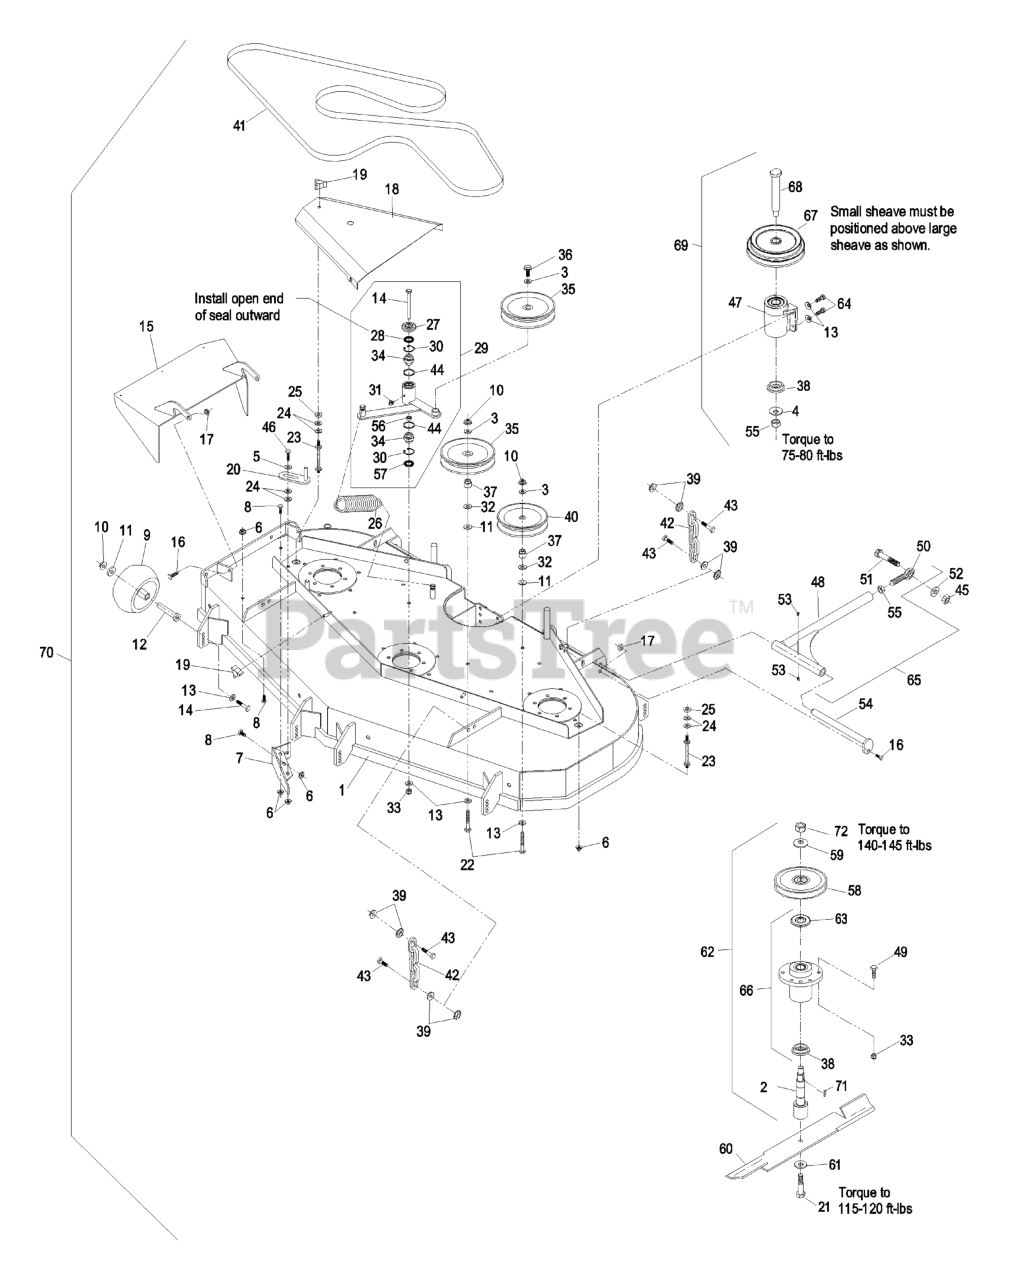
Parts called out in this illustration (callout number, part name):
1	ASM,DECK W/DECALS XP604
2	SPINDLE,SHORT
3	WASHER-FLAT
4	WASHER-SPRING
5	WASHER-SPRING
7	WLD,BAFFLE DISCHARGE
8	SCREW-HH
9	ROLLER-SCALP, ANTI
10	NUT-HHF, WHIZ
12	BUSHING-ROLLER
13	WASHER-BELLEVILLE
14	SCREW-HH
15	WLD,CHUTE XP604
16	SCREW-HH
17	NUT-LOCK, NI
18	SHIELD,BELT
19	KNOB-3 PRONG
20	GUIDE-BELT
21	SCREW-CAP
22	SCREW-HH
23	STUD-SHIELD, BELT (SHORT)
24	WASHER-FLAT
27	GUARD-TOP
28	SEAL-LIP, SINGLE
29	KIT,DECK IDLER LZ/XP
30	RING-SNAP
31	FITTING-GREASE, 90 DEG
32	WASHER-FLAT
33	NUT-LOCK, NI
34	BEARING-SPHERICAL
36	SCREW-HHF
37	BUSHING-IDLER
38	SPACER-GUARD, BOTTOM
40	PULLEY-IDLER
41	BELT,BLADE DRIVE
42	CHAIN-LIFT, DECK
43	SCREW-HH
45	NUT-HEX
46	SCREW-HH
49	SCREW-HH
50	BALLJOINT-SPHERICAL
51	SCREW-HH
52	WASHER-LOCK
53	FITTING-GREASE
54	PIN-STRUT
55	NUT-HEX
57	SEAL-LIP, DOUBLE
58	SHEAVE,BLADE DRIVE 6.30
61	WASHER-BLADE BOLT, HEAVY
63	GUARD-BEARING, TOP
64	SCREW-HH
65	STRUT ASM
67	SHEAVE, JACKSHAFT DOUBLE
68	JACKSHAFT
69	KIT,JACKSHAFT 60/72-3750
70	Asm, Deck Complete
